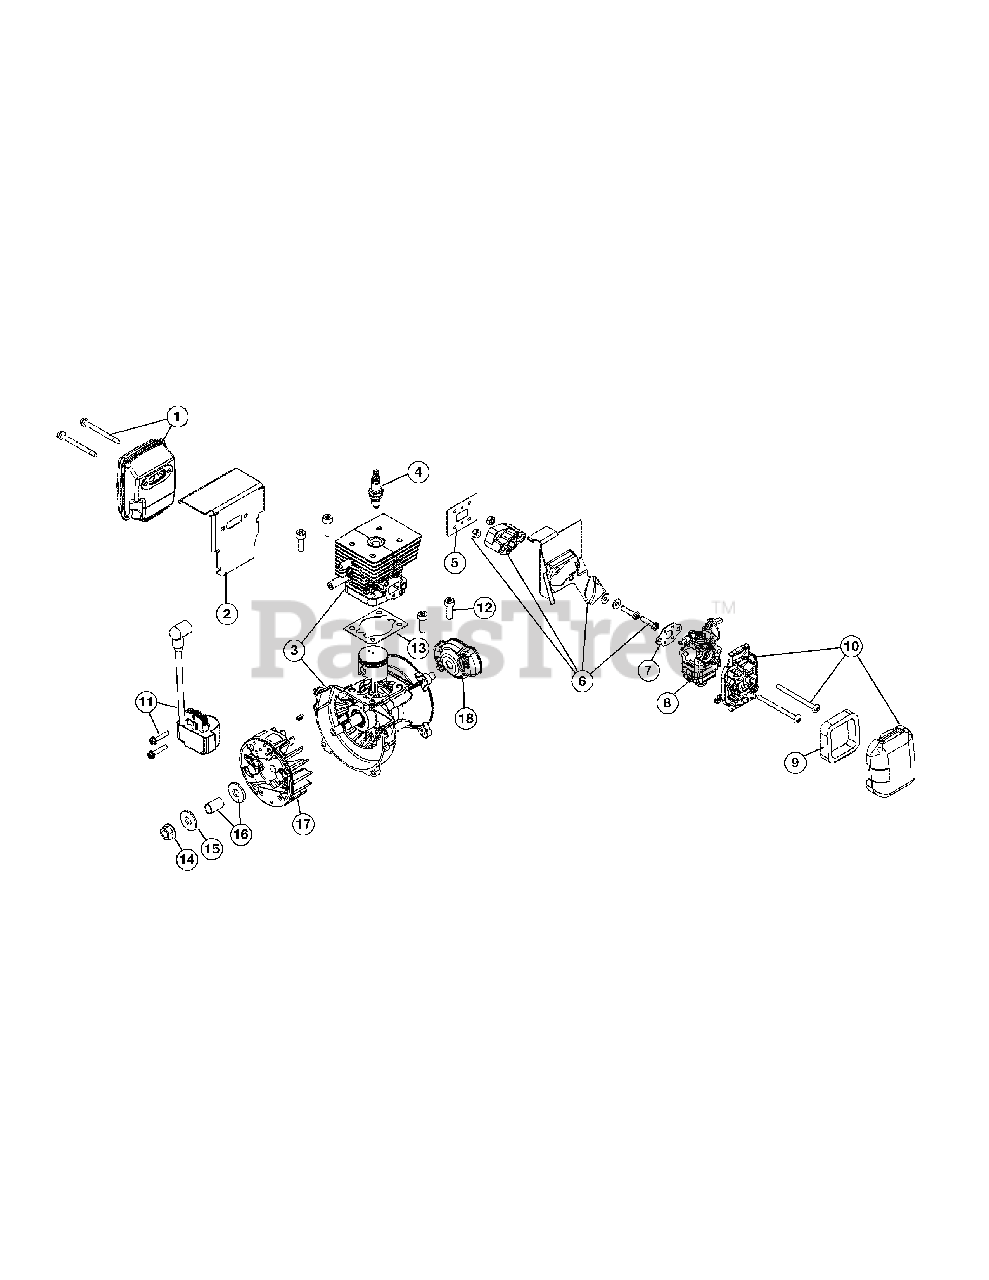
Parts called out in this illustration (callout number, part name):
1	Muffler Assembly
2	Muffler Gasket
3	Shortblock Assembly
4	Spark Plug
5	Insulator Gasket
6	Insulator Assembly
7	Carburetor Gasket
8	Carburetor Assembly
10	Aircleaner Assembly
11	Module Assembly
13	Cylinder Gasket
14	Flywheel Adapter
15	Washer
17	Flywheel Assembly
18	Pawl Assembly
